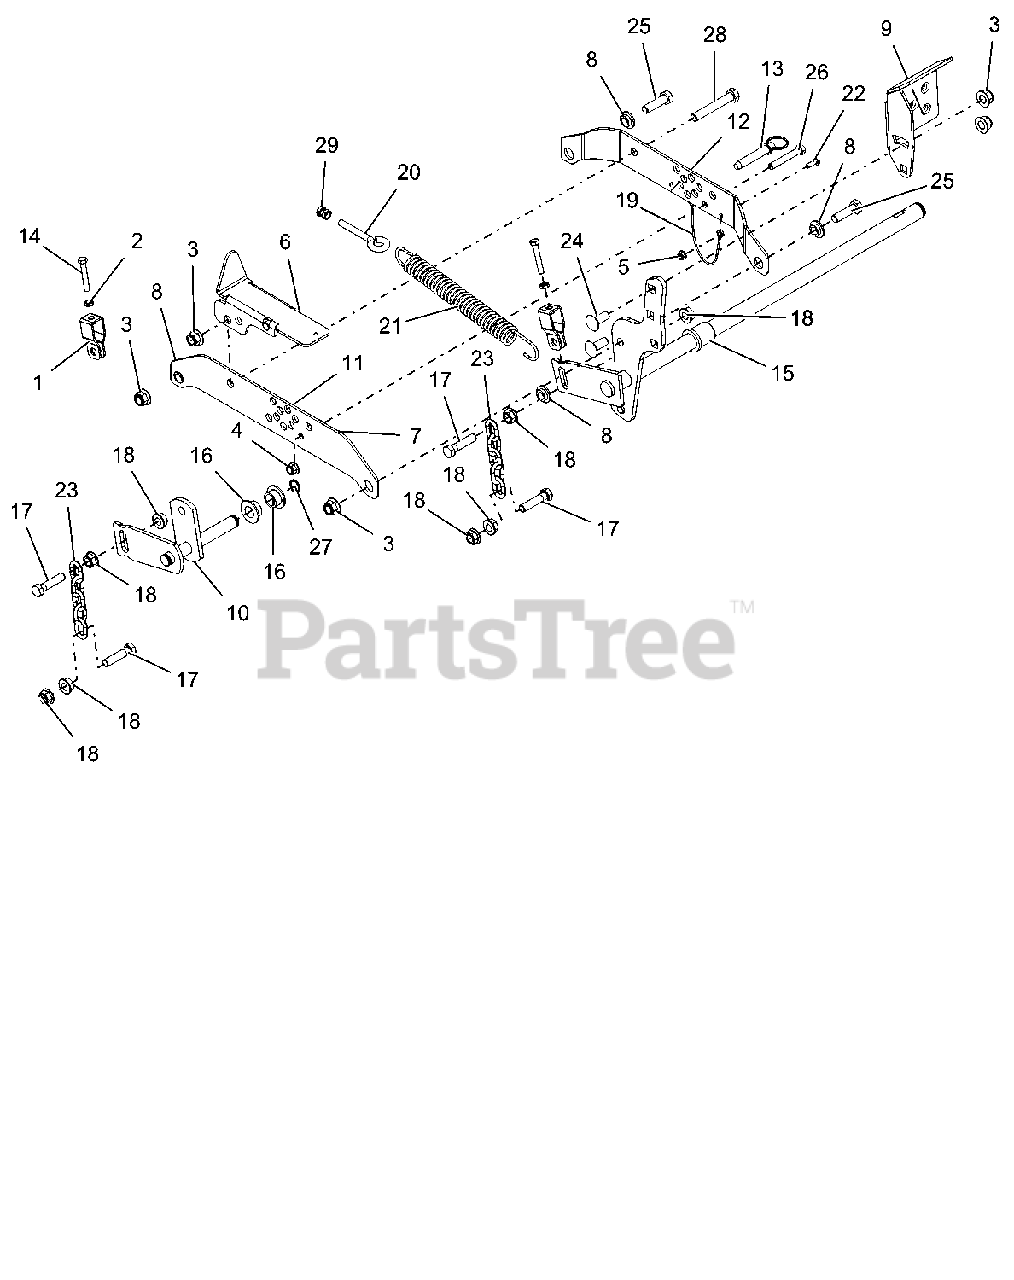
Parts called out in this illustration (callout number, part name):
1	BRKT, DECK LEVELING
2	NUT- JAM .312-18 YWZC
3	@NUT-LK-NYL-FLG .50-13 YWZC
4	@NUT-LK-NYL-FLG .38-16 YWZC
5	@NUT-LK-NYL-FLG .25-20 YWZC
6	MECHANICAL LOCK-UP WMT - BLACK
7	SPACER, .375 X .625 X 1.54
8	BSHG-FLG .515X.750X.395X1.120
9	PEDAL, FOOT
10	WLDMT, REAR RH DECK LIFT ARM
11	RH OUTBOARD LIFT/HOC BRKT -BLK
12	RH INBOARD LIFT/HOC BRKT -BLK
13	PIN, .50 X 2.00 USABLE LG BALL
14	BLT-HEX .312-18X2.00 FTH GR5YZ
15	BSHG-FLG 1.00X1.25X1.50X1.50
16	BSHG-FLG .762X1.0X.580X1.48 NY
17	BLT, HEX M12-1.75X50 CLS8.8 YZ
18	NUT-SPNLK-FLG M12-1.75 YZ
19	CABLE, 12.0 LANYARD, NYLON
20	BLT-EYE .375-16X2.50 YWZC
21	SG-TENS .162X1.25X8.25 WLD 25
22	@BLT-HEX .25-20X.75 GR5 YWZC
23	CHAIN, LINK
24	@BLT-RDHDSQNK .50-13X1.25 G5YZ
25	@BLT-HEX .50-13X1.75 GR5 YWZC
26	@BLT-HEX .38-16X2.50 GR5 YWZC
27	RG-RTNG-EXT .689X.078
28	@BLT-HEX .50-13X3.25 GR5 YWZC
29	NUT-HEX-JAM .375-16 YWZC
